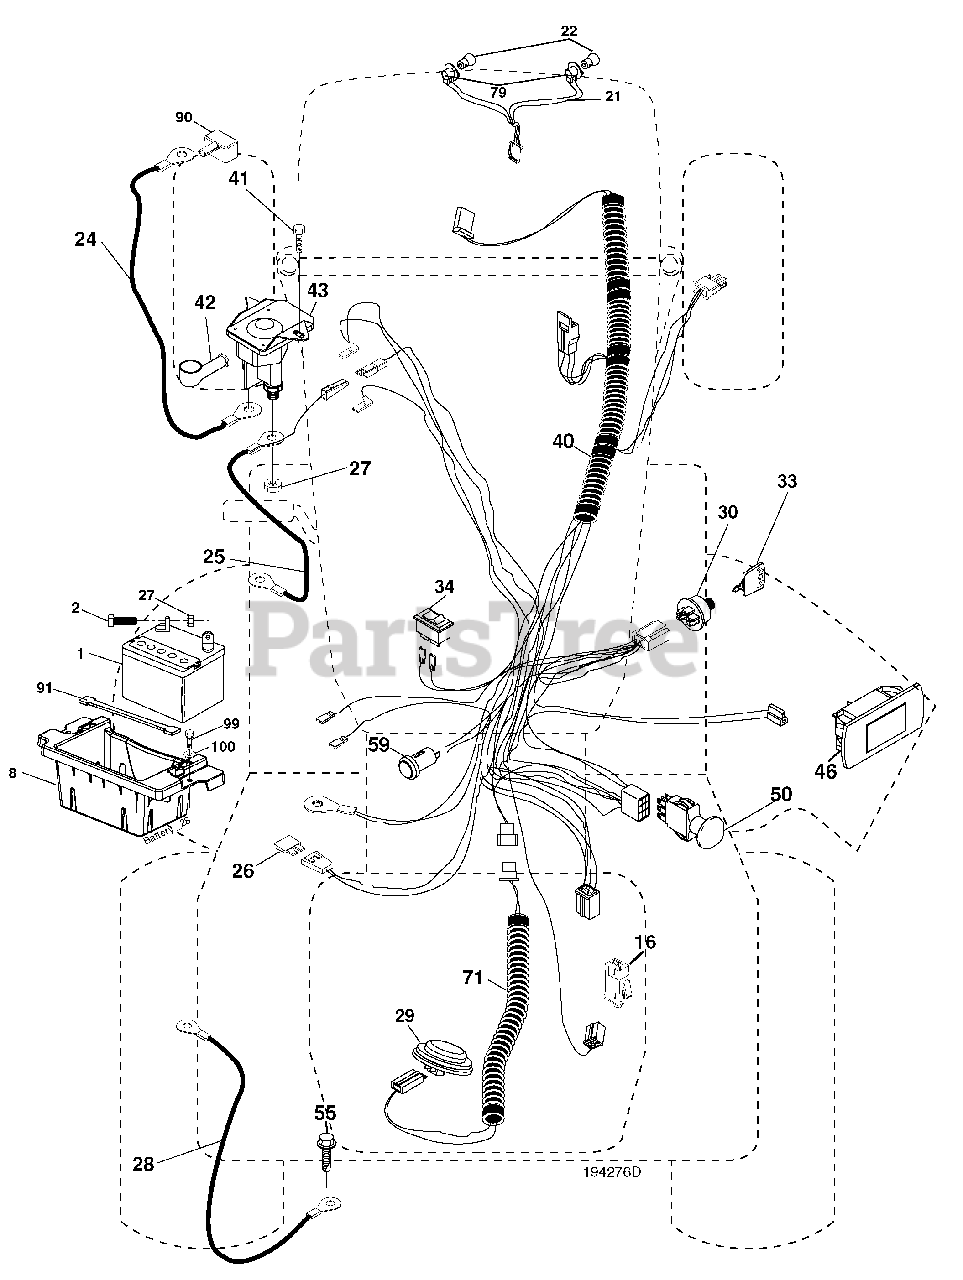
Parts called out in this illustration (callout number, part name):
1	Battery
2	Bolt Hex Head 1/4-20 x 3/4
8	Box Battery
16	Switch Interlock Push-In
21	Harness Socket Light W/4152J
22	Bulb Light
24	Cable Battery
25	Cable Start Red
26	Fuse
27	Nut Keps Hex 1/4-20 unc
28	Cable, Ground
29	Switch, Seat
30	Switch, Ignition
33	Key, Ignition
34	Switch Light / Reset
40	Harness Ignition
41	Screw Thd Cut 1/4-20 x 1/2
42	Cover, Terminal
43	Solenoid
46	Gauge Hourmeter
50	Switch, PTO
55	Screw Thdrol 5/16-18 x 3/4 TYTT
59	Outlet 12-Volt
71	Harness Ign. Dash
79	Bulbholder Asm. Incan Descent
90	Cover Terminal Battery
91	Strap Battery Mount Front
99	Screw Hexwsh Thdrol 1/4-20 x 3/4
100	Washer 9/32 x 7/8 x 16 Ga.
